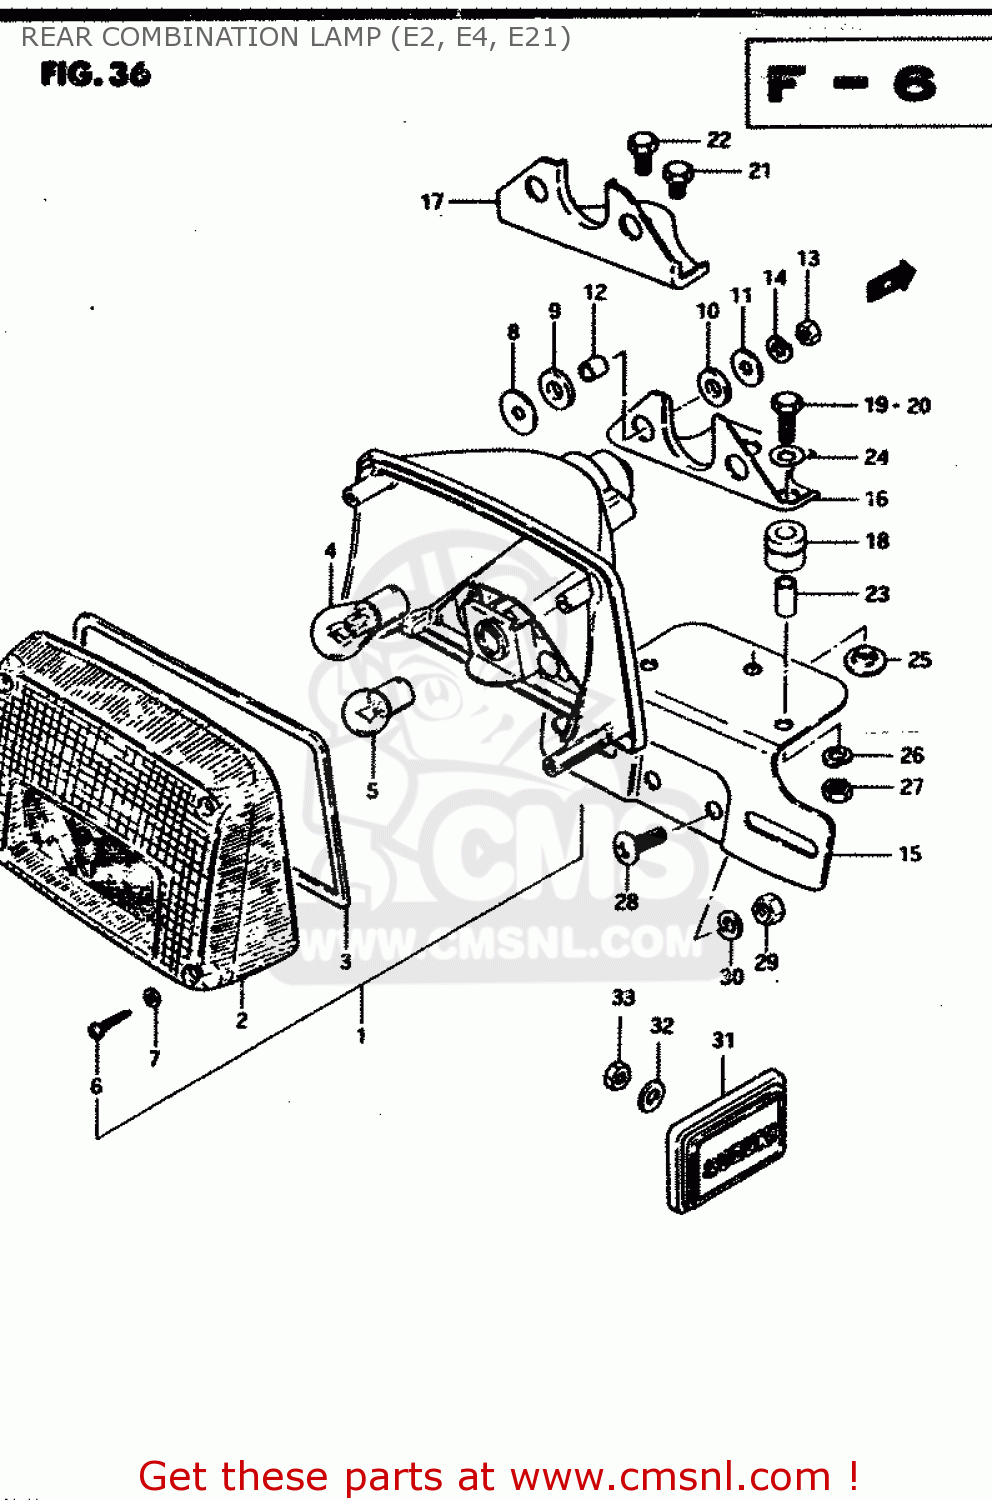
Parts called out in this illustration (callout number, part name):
1	LAMP, REAR COMBINATION
2	LENS,RR COMBI
3	GASKET (NAS)
4	BULB(12V21/5W)
5	BULB
6	SCREW,REAR COMBINATION LAMP
7	GASKET (NAS)
8	WASHER
9	CUSHION
10	CUSHION
11	WASHER(6,5X22X1.6)
12	SPACER(6.1X9X7.5)
13	NUT
14	LOCK WASHER
15	BRACKET, LICENCE PLATE
16	BRACKET,LICENSE PLATE
17	BRACKET,REAR COMBINATION LAMP
18	CUSHION, BRACKET
19	BOLT
20	BOLT
21	BOLT
22	BOLT, UPPER
23	SPACER (6.4X9X15.5)
24	WASHER
25	WASHER
26	LOCK WASHER
27	NUT
28	SCREW
29	NUT
30	LOCK WASHER
31	EMBLEM, REAR SIDE
32	WASHER
33	NUT
